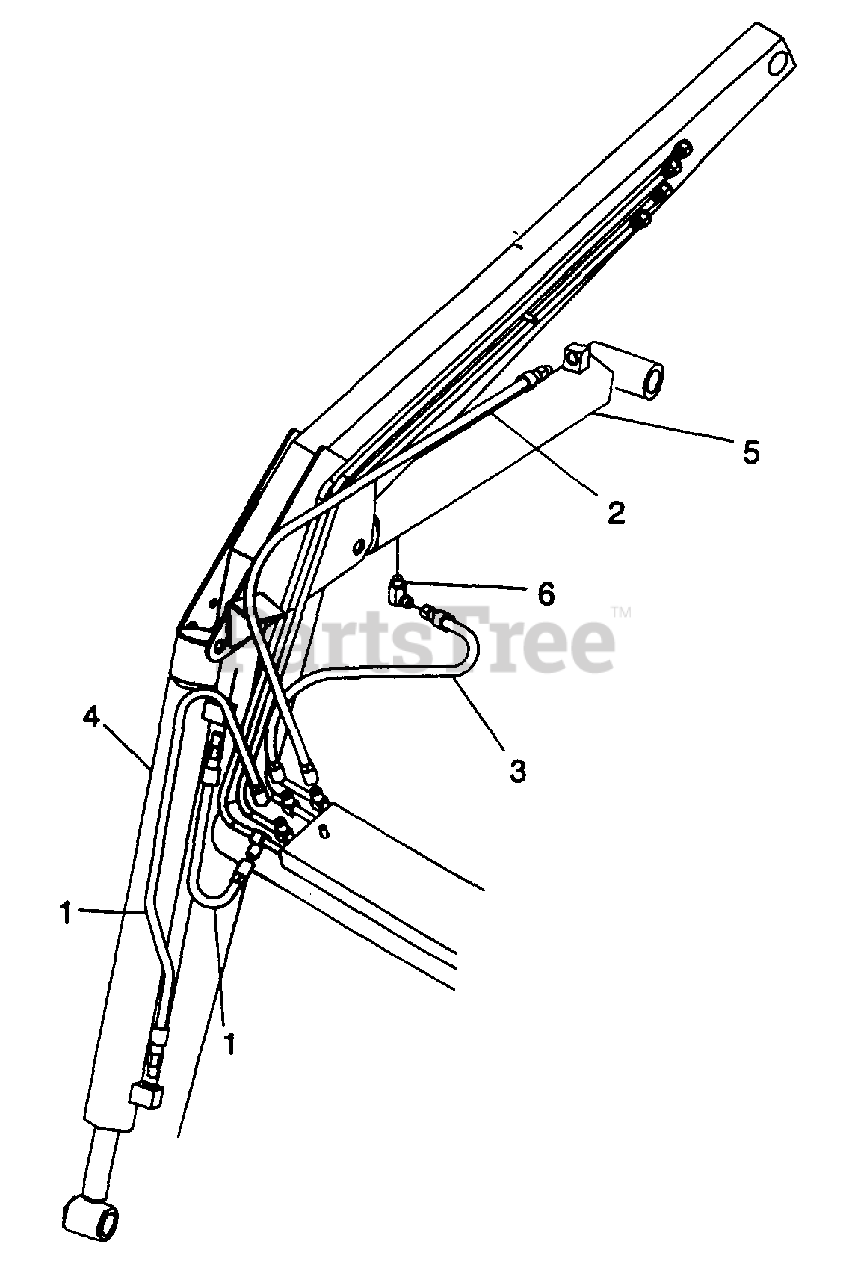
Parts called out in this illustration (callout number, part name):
4	Hydraulic cylinder, 13.75" long
5	Hydraulic cylinder, 19.38" long
6	Elbow, 9/16 JICM 9/16 ORB
